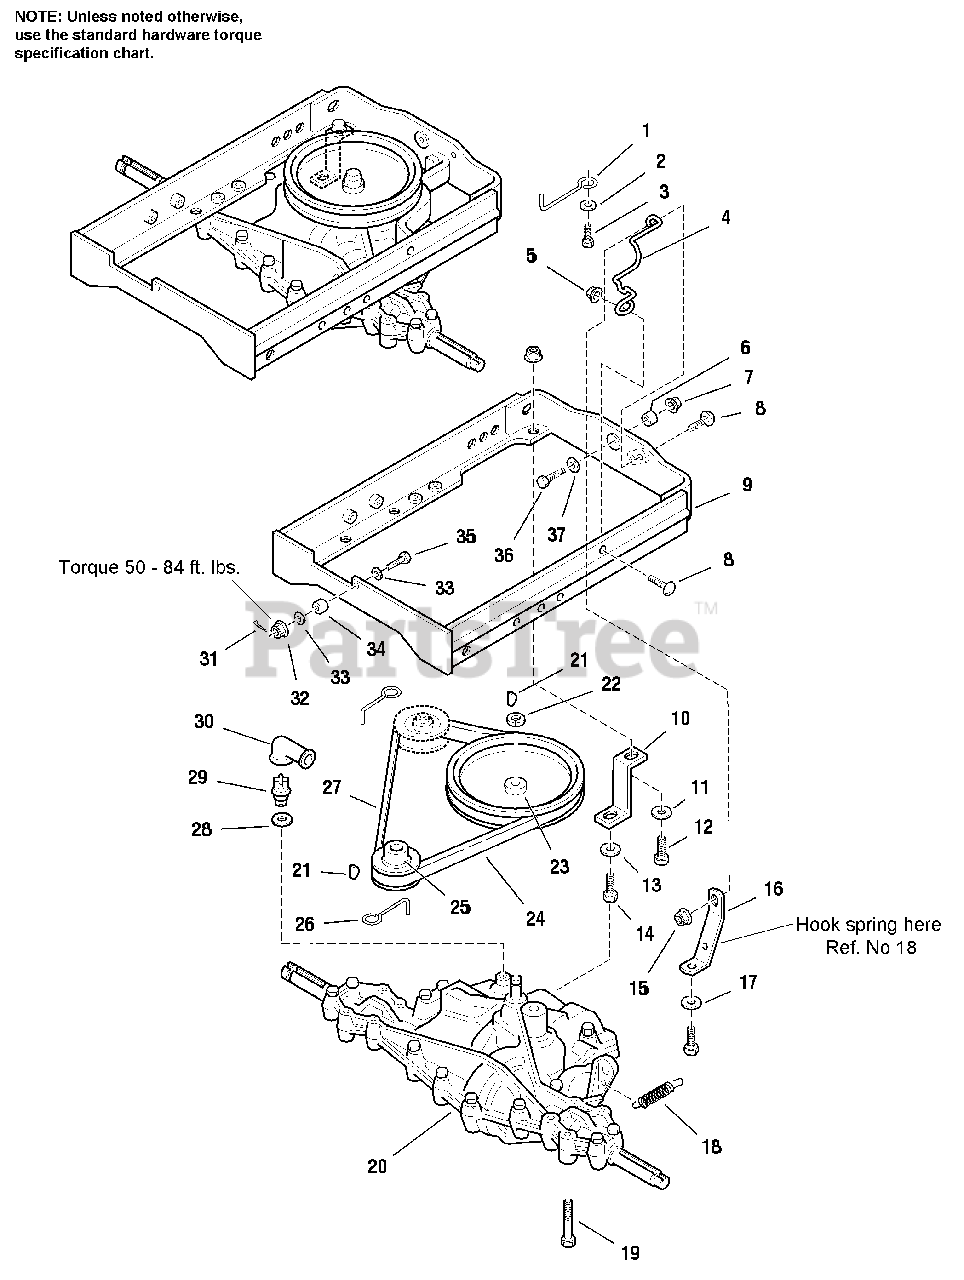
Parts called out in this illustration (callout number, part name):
1	BELT STOP
2	WASHER, Plain, 13/32 x 1 x 1/8
3	CAPSCREW, Hex Hd., 3/8-16 x 1-3/4
4	GUIDE, Belt, Transmission
5	NUT, Hex FLG LK 2 -wax 5/16 x 18
6	BUSHING, Rear
7	NUT, Hex, Flange Lock, 1/2 x 13
8	CARRIAGE BOLT, 5/16-18 x 5/8
9	CARRIER ASSY
10	STRAP, Torque
11	WASHER, Plain, 5/16
12	SCREW, Hex, Flange, Whizlock, 5/16-18 x 3/4
13	WASHER, Plain, 7/16 x 1-1/4 x 1/8
14	SCREW, Hex Hd., Taptite, 3/8-18 x 5/8
15	NUT, Hex, Flange, Whizlock, 5/16-18
16	STRAP, Torque
17	WASHER, Plain, 13/32 x 7/8 x 5/64
18	SPRING, Return
19	SCREW, Hex Hd., 5/16-18 x 2-1/4
21	KEY, Woodruff, #9
22	RING, Retaining
23	PULLEY ASSY., Driven, Transmission
25	PULLEY ASSY., Drive, Engine
28	WASHER, Plain, 21/32 x 1-1/4 x 1/16
29	SWITCH, Ball N.O.
30	COVER, Terminal
31	PIN, Cotter 1/8 x 1-1/2
32	NUT, Hex Hd., 1/2 x 20
33	WASHER, Belleville 1/2
34	BUSHING, Front
35	CAPSCREW, Hex Hd., 1/2-20 x 1-3/4
36	CAPSCREW, Hex Hd., 1/2-13 x 1-1/4
37	WASHER
